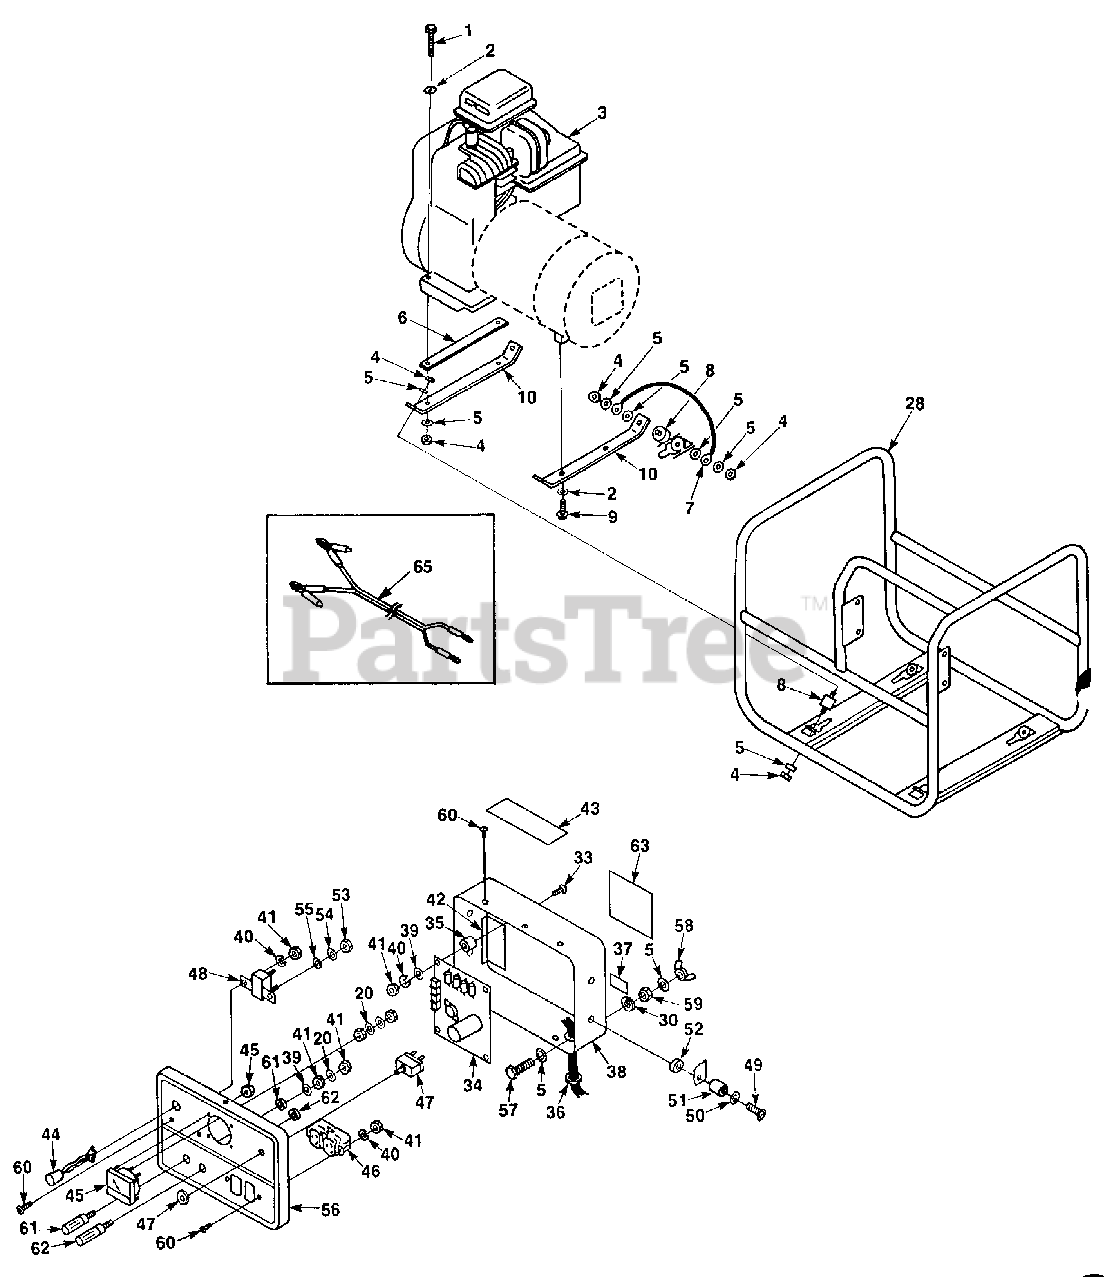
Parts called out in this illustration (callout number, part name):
1	SCREW- Hex Hd. 5/16-18 x 1 1/2"
2	WASHER- Lock Int. 5/16
3	ENGINE-5 H.P. Briggs
4	NUT- Hex 5/16-18
5	WASHER-lnt.
7	STRAP-Ground
8	ISOLATOR-Vibration
9	SCREW-Hex taptite 5/16-18 x 1"
10	SUPPORT-Eng. & Gen.
20	WASHER-Lock Int. #8
28	ROLL CAGE
30	WASHER- Lock 5/16"
33	SCREW- #8- 32 x 5/8"
34	VOLTAGE REGULATOR
35	SPACER- 1/4"
36	GROMMET
37	DECAL-Ground
38	CONTROL BOX
39	WASHER-Flat #8
40	WASHER-Lock #8
41	NUT- Hex 8-32
42	DECAL-Schematic
43	DECAL- Warning
44	PILOT LITE
45	VOLTMETER
46	RECEPTACLE- Duplex
47	BREAKER- Circuit (AC)
48	BREAKER- Circuit (DC)
49	SCREW- Pan hd. 1/4-20 x 3/4"
50	WASHER- Flat 1/4"
51	SLEEVE- Grommet
52	GROMMET- Isolator
53	NUT- Hex 10-32
54	WASHER- Flat #10
55	WASHER- Lock #10
56	CONTROL PANEL
57	SCREW- Cap hex hd. 5/16-18 x 1"
58	NUT- Wing 5/16-18
59	NUT- Hex 5/16-18
60	SCREW- Pan hd., 8-32 x 3/8"
61	POST- Binding (Black)
62	POST- Binding (Red)
63	DECAL- Caution
65	LEAD- D.C.
